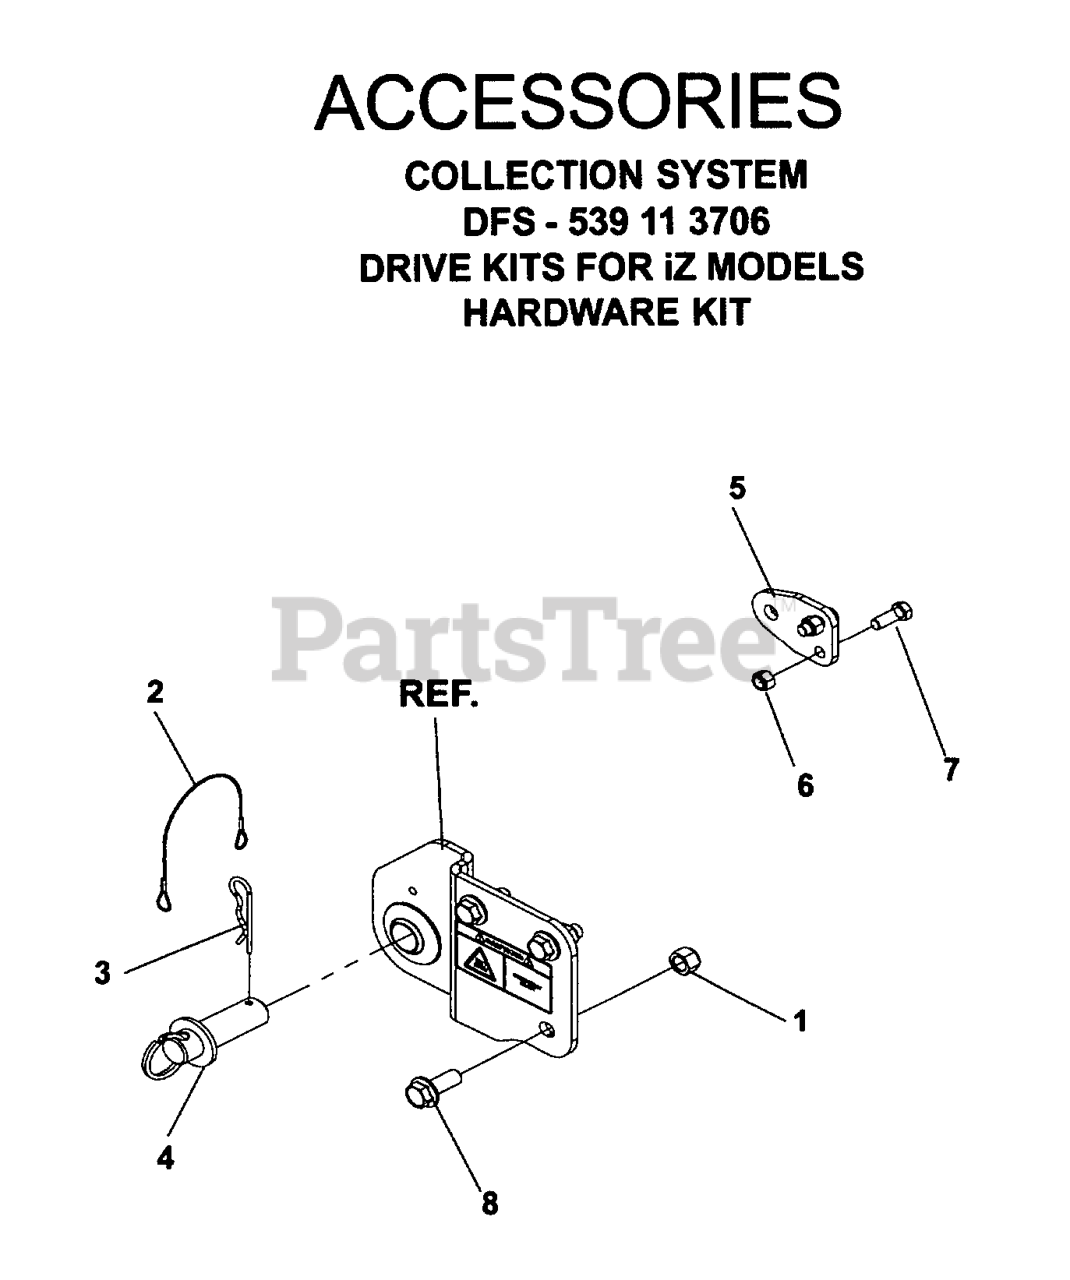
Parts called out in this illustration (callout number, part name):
1	NUT 1/2-13 HEX NYLOC ZD
5	SUPPORT BRACKET
6	NUT 3/8-16 NYLOC
7	HCS 3/8-16X1.GRD.5.ZD
8	HCS 1/2C X 1 1/4 SERRATED HEAD
